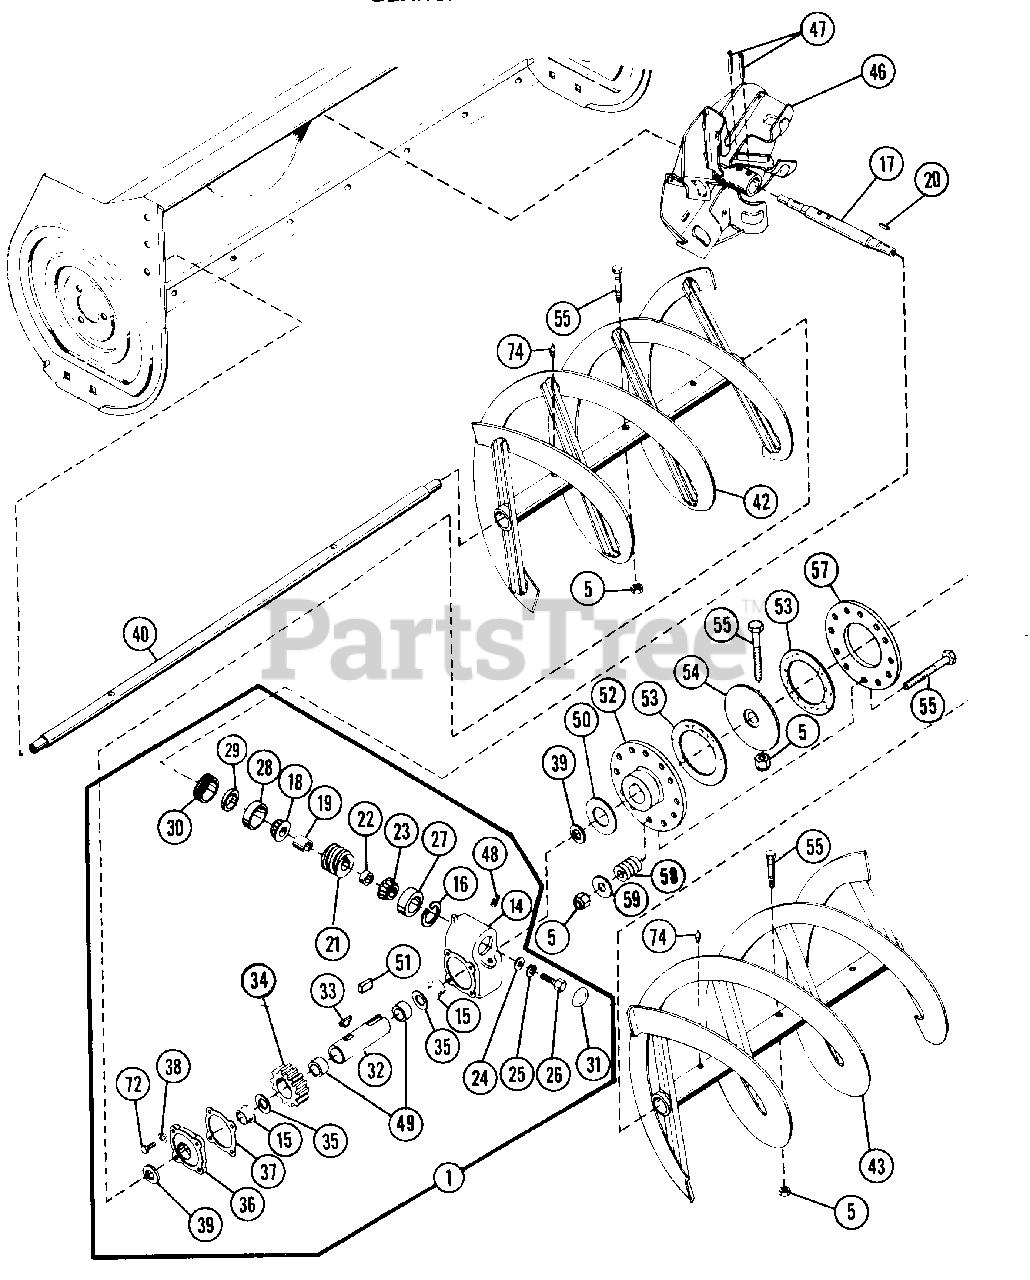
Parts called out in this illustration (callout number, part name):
1	GEARCASE ASSEMBLY
5	NUT, LOCK 5/16-18
14	GEAR CASE
15	BUSHING, FLANGE 1.62X1.87X11
16	RING, SNAP INTERNAL 1.781
17	WORM SHAFT
18	BEARING CONE
19	BEARING SPACER
20	KEY, STRAIGHT SAE 1035
21	WORM
22	SPACER, BEARING
23	BEARING CONE
24	WASHER, FLAT .344X.688X.065
25	WASHER, LOCK 3/8 SP HEAVY
26	BOLT, HEX 5/16-18X.75
27	BEARING CUP
28	BEARING CUP
29	SEAL
30	ADJUSTMENT PLUG
31	CAP, DUST
32	GEARCASE SHAFT
33	KEY, FEATHER
34	GEAR, WORM
35	WASHER, 1.625X2.50X.012
36	COVER, GEAR CASE
37	GASKET
38	WASHER, LOCK 1/4 EXT TH TYA
39	SEAL
40	32" RAKE SHAFT
42	RIGHT RAKE
43	LEFT RAKE
46	FAN
47	PIN, ROLL 5/16X1.75
48	PIPE PLUG
49	BUSHING, SLEEVE
50	WASHER
51	KEY, STRAIGHT
52	DRIVER
53	FRICTION DISC
54	DRIVER PLATE
55	BOLT, HEX 5/16-18X2.00
57	PRESSURE PLATE
58	SPRING, COMPRESSION
59	WASHER, FLAT
72	BOLT, HEX 1/4-20X.875
74	SPIN DRIVE ZERK FITTING
